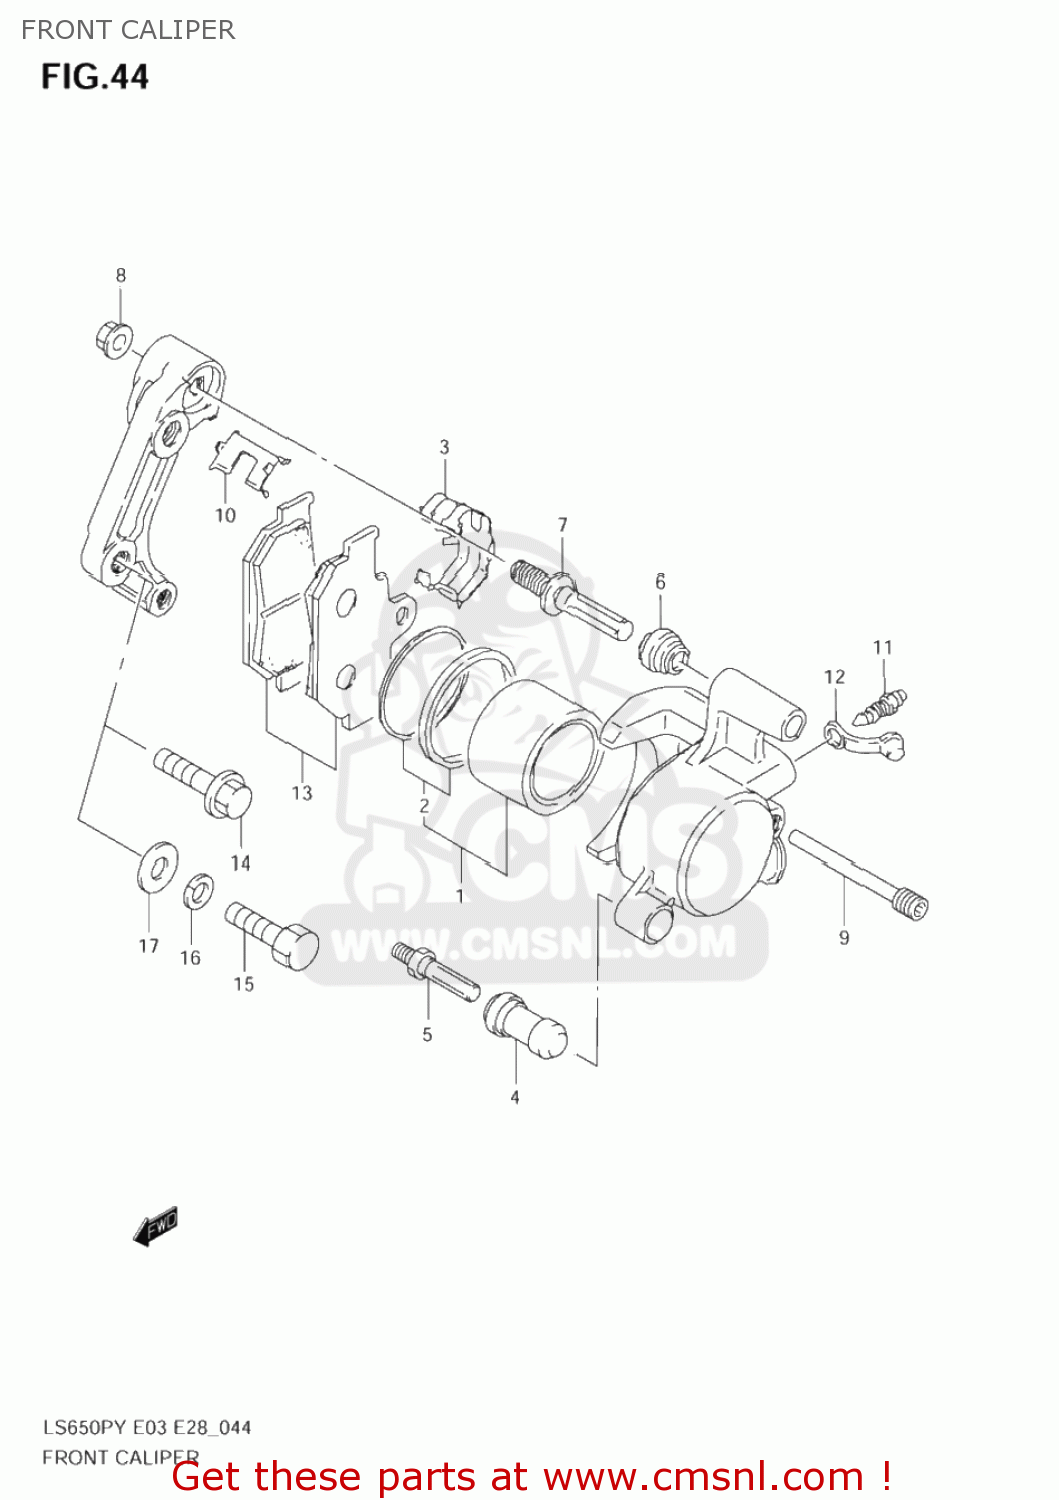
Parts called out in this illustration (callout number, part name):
1	PISTON SET
2	SEAL SET,PISTON
3	SPRING
4	BOOT
5	BOLT
6	BOOT
7	PIN,SLIDE
8	NUT,SLIDE PIN
9	PIN,HANGER
10	RETAINER
11	BLEEDER
12	CAP,BLEEDER
13	PAD SET (NAS)
14	BOLT 10X38
15	BOLT(10X38)
16	WASHER,LOCK
17	WASHER
